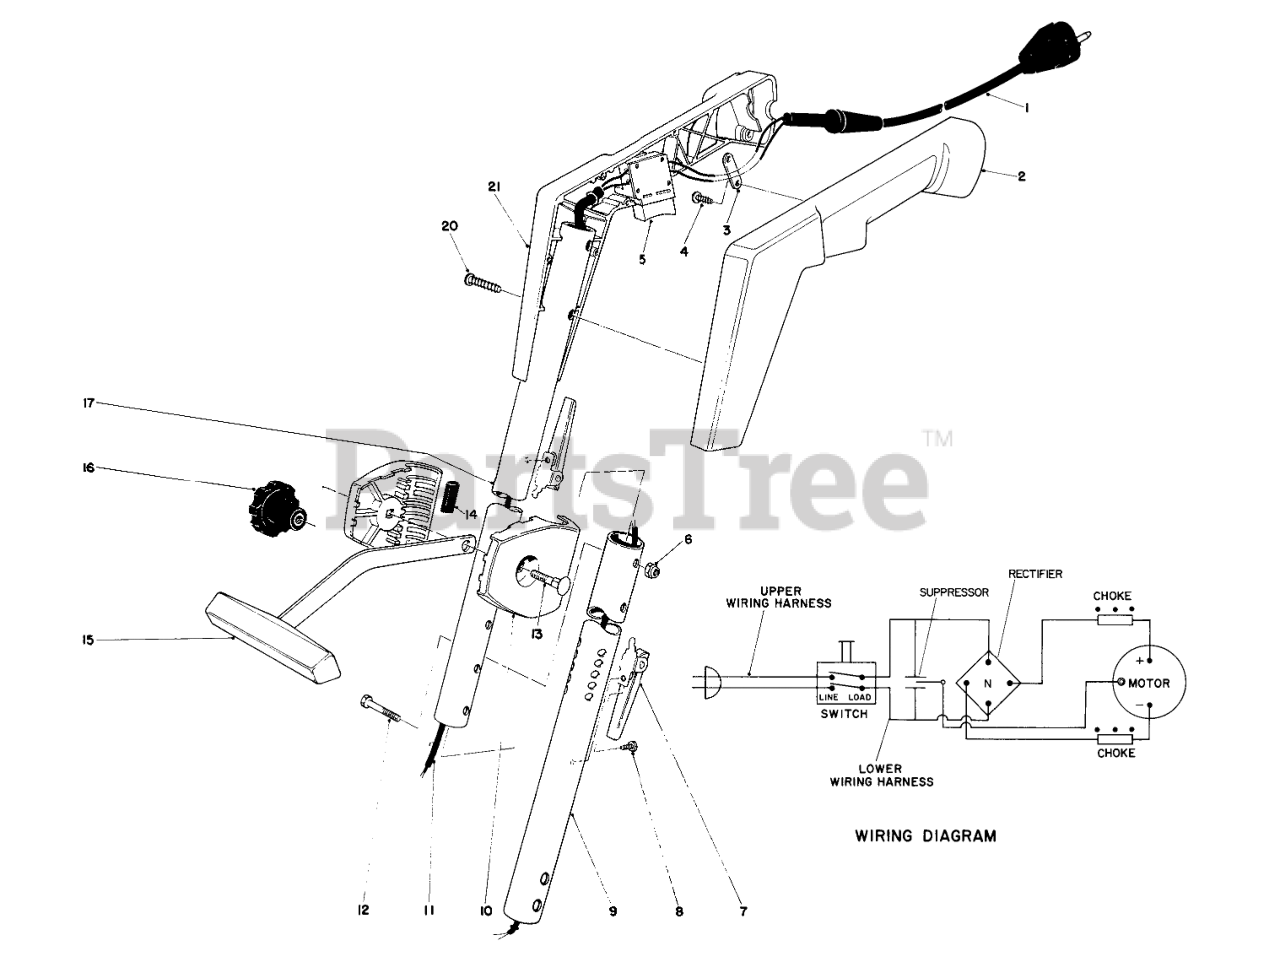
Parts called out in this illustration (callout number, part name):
1	Power Cord
2	Left Hand Grip
3	Clamp
4	SCREW-PPH
5	Switch
6	NUT-LOCK, NI
7	Clamp, Storage
8	Screw-Phcr
9	Lower Tubing
10	T-HANDLE BRKT(RED)
11	Wiring Harness
12	Screw
13	BOLT-CARR
14	RUBBER INSERT
15	Tee Handle
17	Upper Tubing
19	Right Hand Grip
